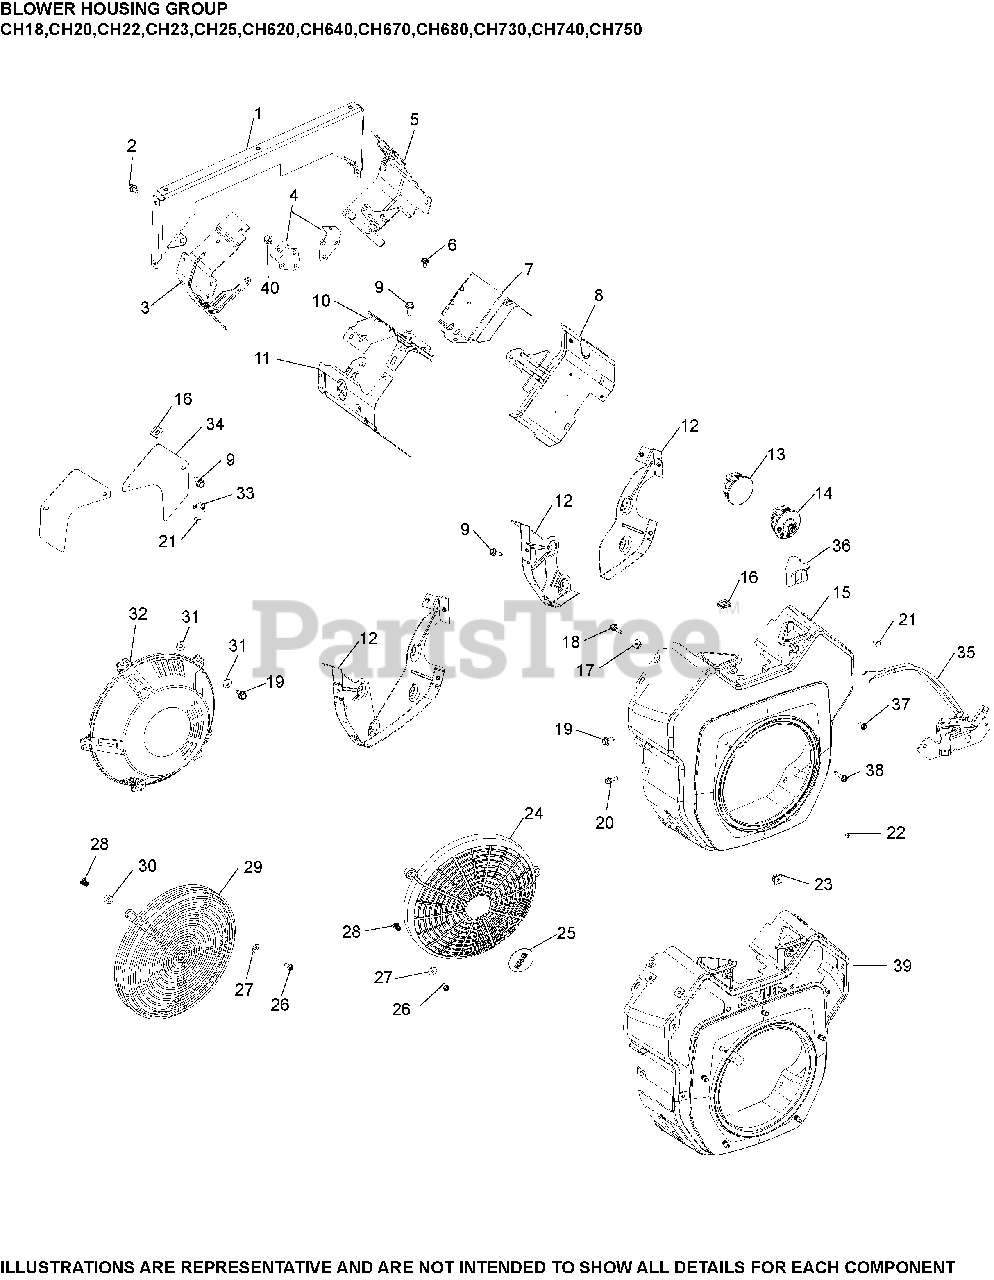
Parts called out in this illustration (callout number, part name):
6	SCREW, THREAD FORMING
7	BAFFLE, VALLEY #1 CYLINDER
8	KIT, CYL BAFFEL #1 SIDE
9	SCREW, THREAD FORMING
10	BAFFLE, VALLEY #2 CYLINDER
11	KIT, CYL BAFFEL #2 SIDE
12	KIT, BACKING PLATE
15	HOUSING, BLOWER
19	SCREW, THREAD FORMING
